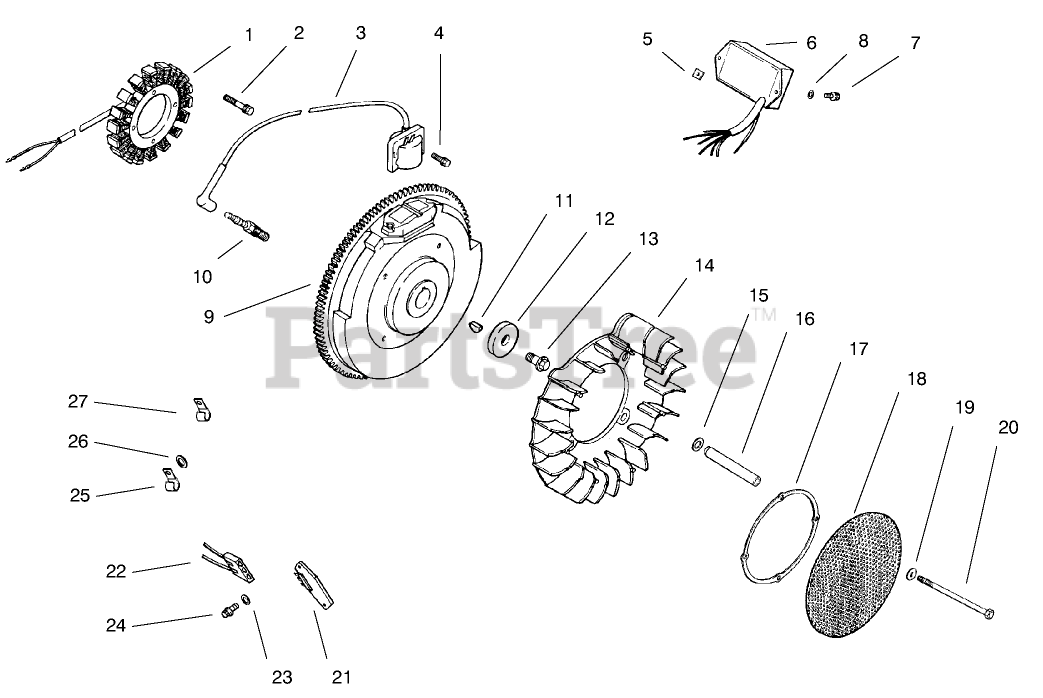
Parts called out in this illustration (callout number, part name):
1	Stator-15 amp
2	Screw
3	Screen-Grass
4	Screw-HSH
5	Nut-Plastic
6	Module, speed adv.
7	Screw, pan head M4.2x13 (2)
8	Washer
9	Flywheel
10	Plug-Spark
11	Key
12	Washer
13	Screw
14	Fan
15	Washer, sping
16	Spacer
17	Ring-Support
18	Screen-Grass
19	Washer
20	Screw-Hex
21	Rectifier-Regulator
22	Connector
23	Washer
24	Screw
25	Clamp
26	Washer
27	Clip
